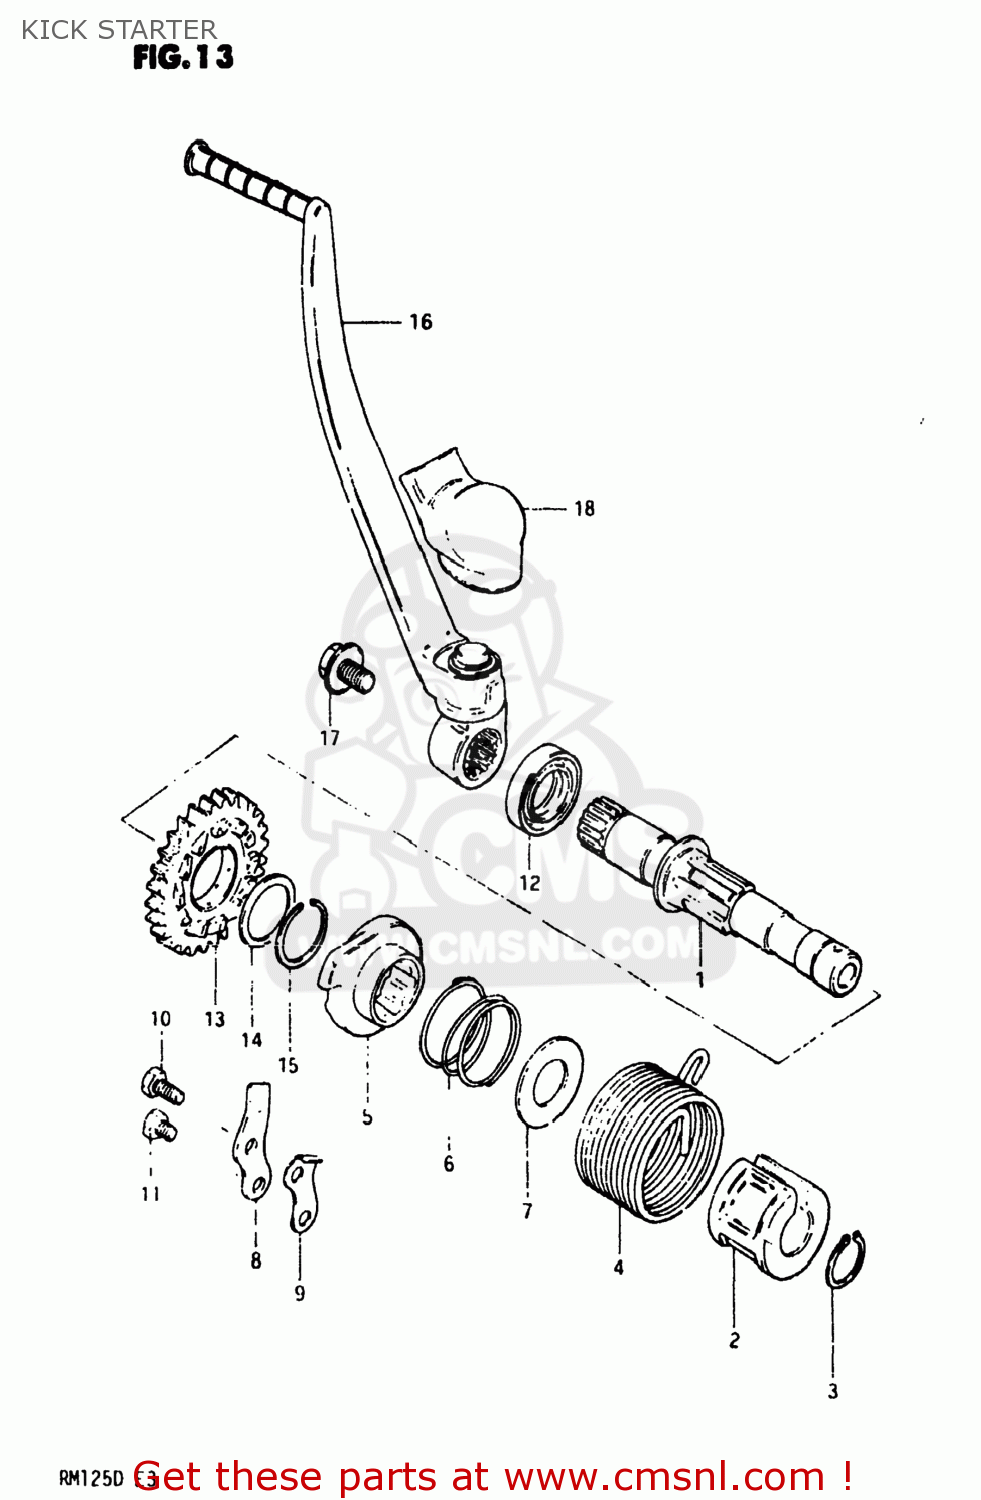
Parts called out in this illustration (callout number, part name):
1	SHAFT,KICK STARTER
2	GUIDE,KICK STARTER SFT SPRING
3	CIRCLIP
4	SPRING
5	STARTER,KICK
6	SPRING
7	WASHER
8	GUIDE,KICK STARTER
9	STOPPER,KICK STARTER
10	BOLT, UPPER
11	BOLT
12	SEAL,OIL(20X27X5)
13	GEAR,KICK STARTER DRIVE
14	SHIM
15	CIRCLIP
16	LEVER ASSEMBLY,KICK STARTER
17	BOLT(8X14)
18	COVER,KICK STARTER LEVER JOINT
